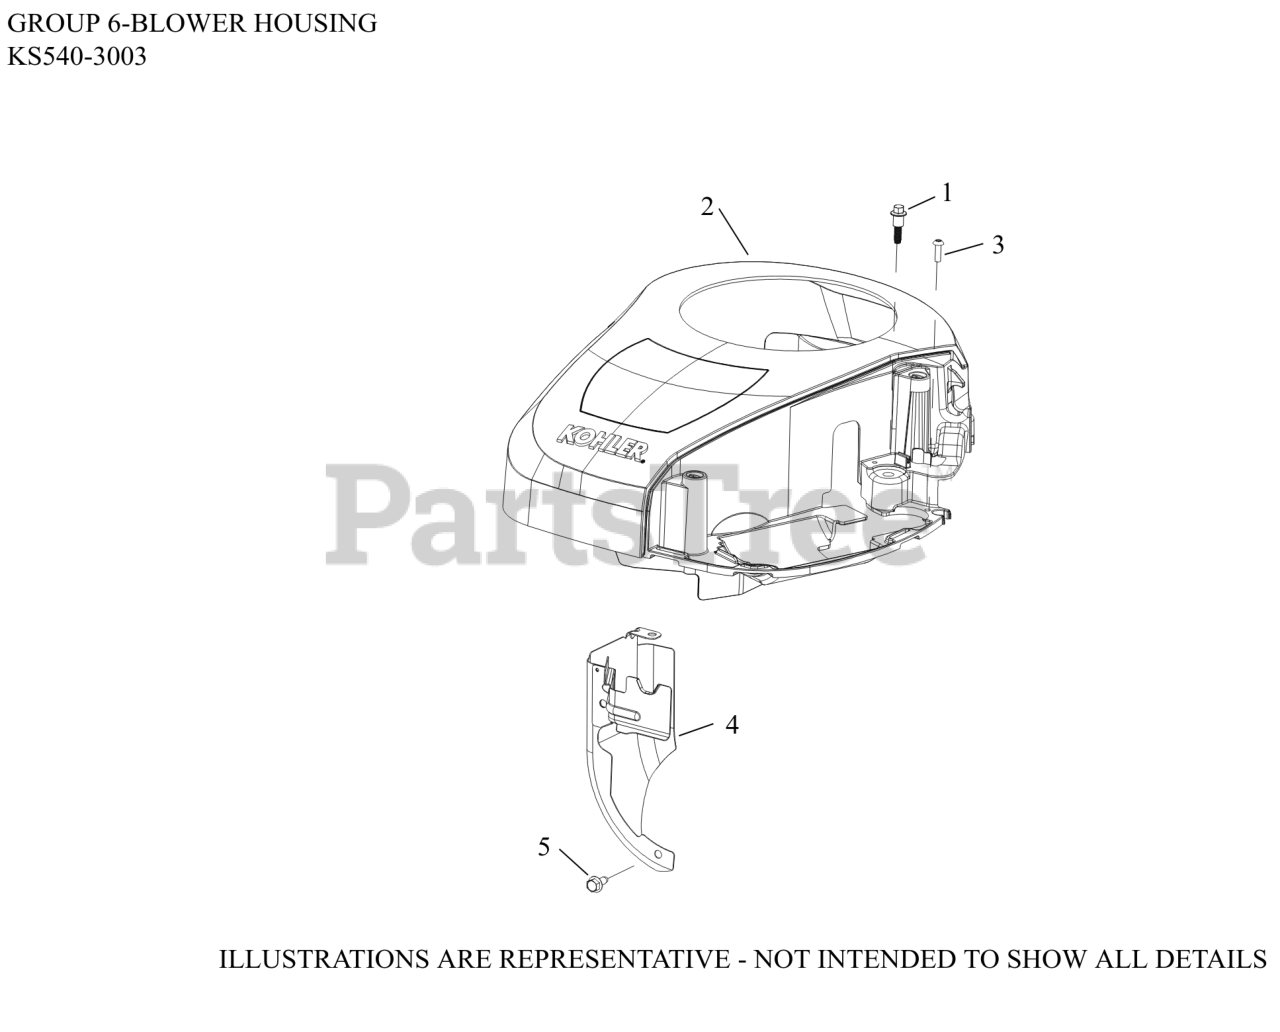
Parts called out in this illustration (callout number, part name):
1	SCREW, SHD THD FRM M6X1X26
2	KIT, BLOWER HOUSING
3	SCREW, HI-LOW
4	BAFFLE, BARREL ASSY
5	SCREW, THREAD FORMING
